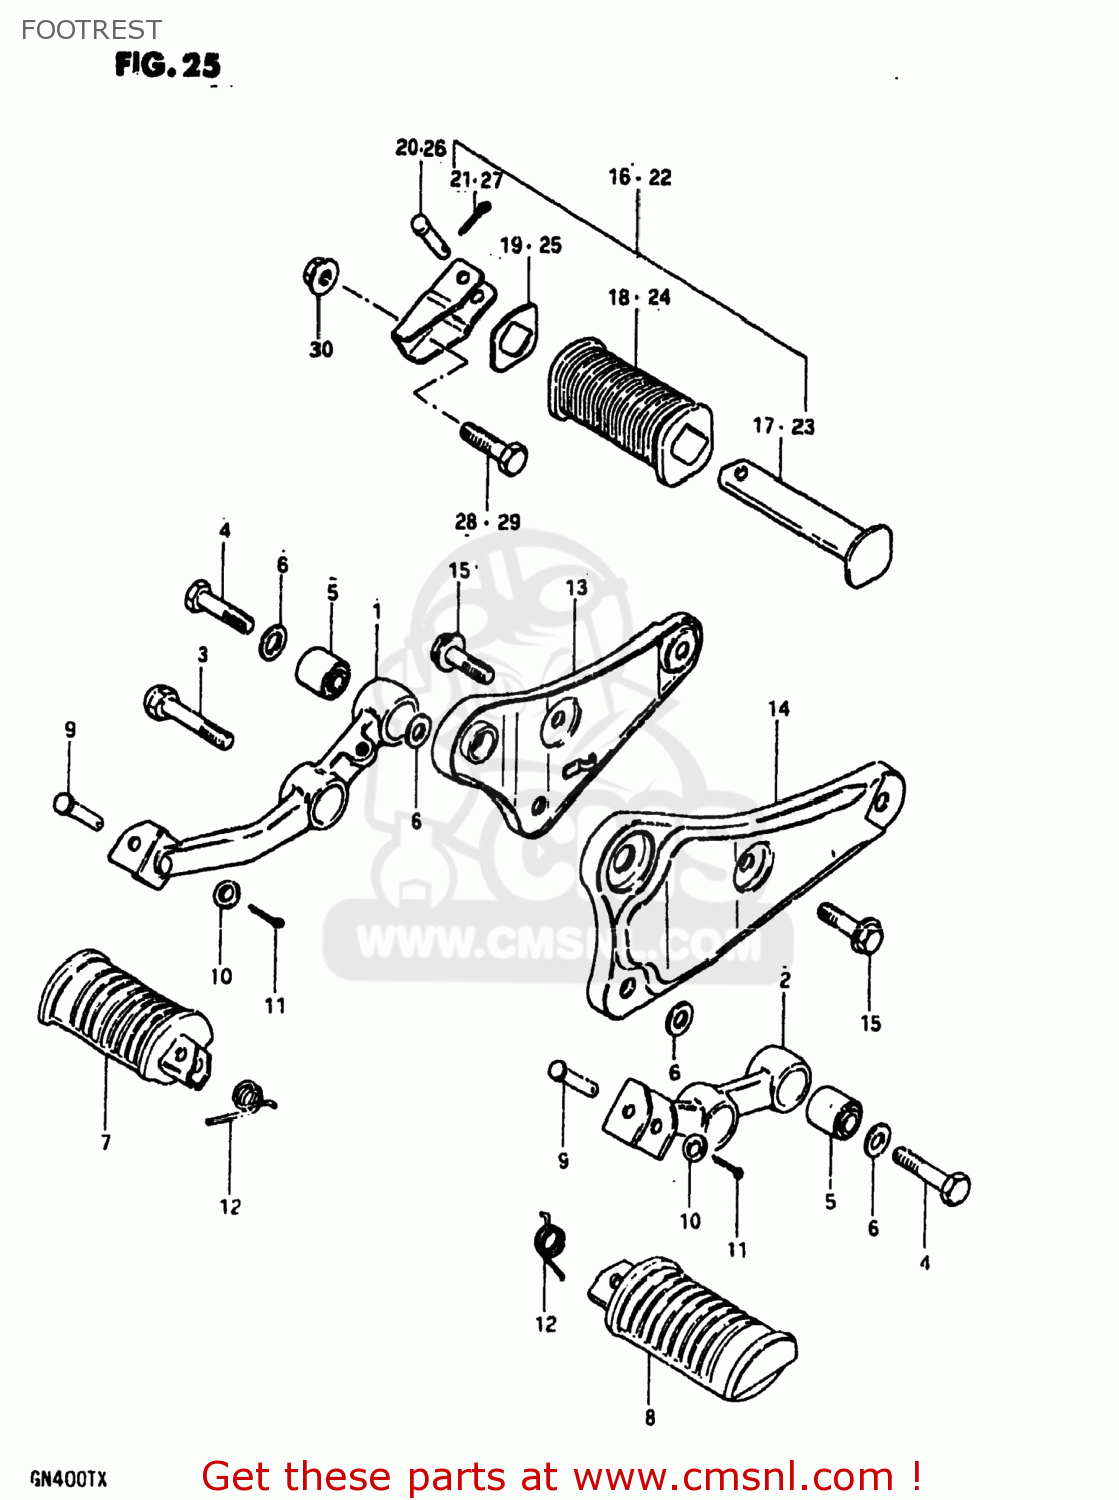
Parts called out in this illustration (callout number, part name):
1	BAR,FRONT FOOTREST
2	BAR,FRONT FOOTREST,LEFT
3	BOLT(10X50)
4	BOLT(10X35)
5	BUSH(10.2X25X19)
6	WASHER
7	RUBBER,FOOTREST
8	FOOTREST
9	PIN
10	WASHER
11	PIN
12	SPRING
13	BRACKET
14	BRACKET
15	BOLT
16	FOOTREST ASSEMBLY,REAR
17	BAR,REAR FOOTREST
18	RUBBER,REAR FOOTREST
19	WASHER,FOOTREST RUBBER
20	PIN
21	PIN
22	FOOTREST ASSEMBLY,REAR,LEFT
23	BAR,REAR FOOTREST,RIGHT
24	RUBBER,PILLION FOOTREST
25	WASHER,FOOTREST RUBBER
26	PIN
27	PIN
28	BOLT
29	BOLT
30	NUT
